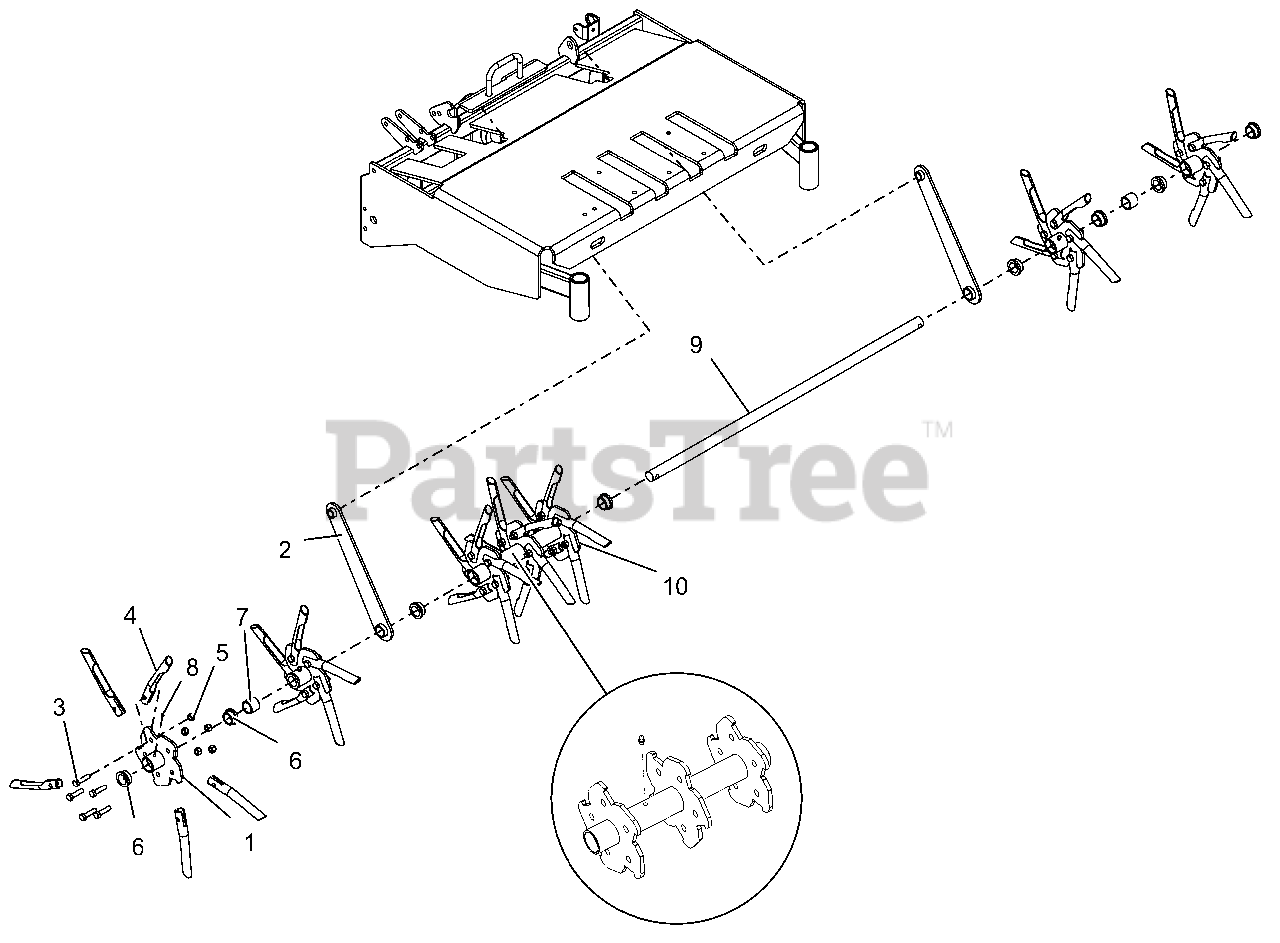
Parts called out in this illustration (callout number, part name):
1	WLDMT, 5 TINE - BLACK
2	WLDMT, PUSH
3	BLT, HEX .38-16X1.50 G5 ZCC
4	SPOON TINE, SINGLE BOLT MNT
5	NUT,NYL .38-16 G5 ZCC
6	BSHG,FLG 1.0 X 1.25 X 1.5 X .6
7	TUBE, SPACER - BLACK
8	FTG-LUBE .25-28X.256 SST
9	SHAFT, CROSS
10	WLDMT, 5 TINE TRIPLE - BLACK
